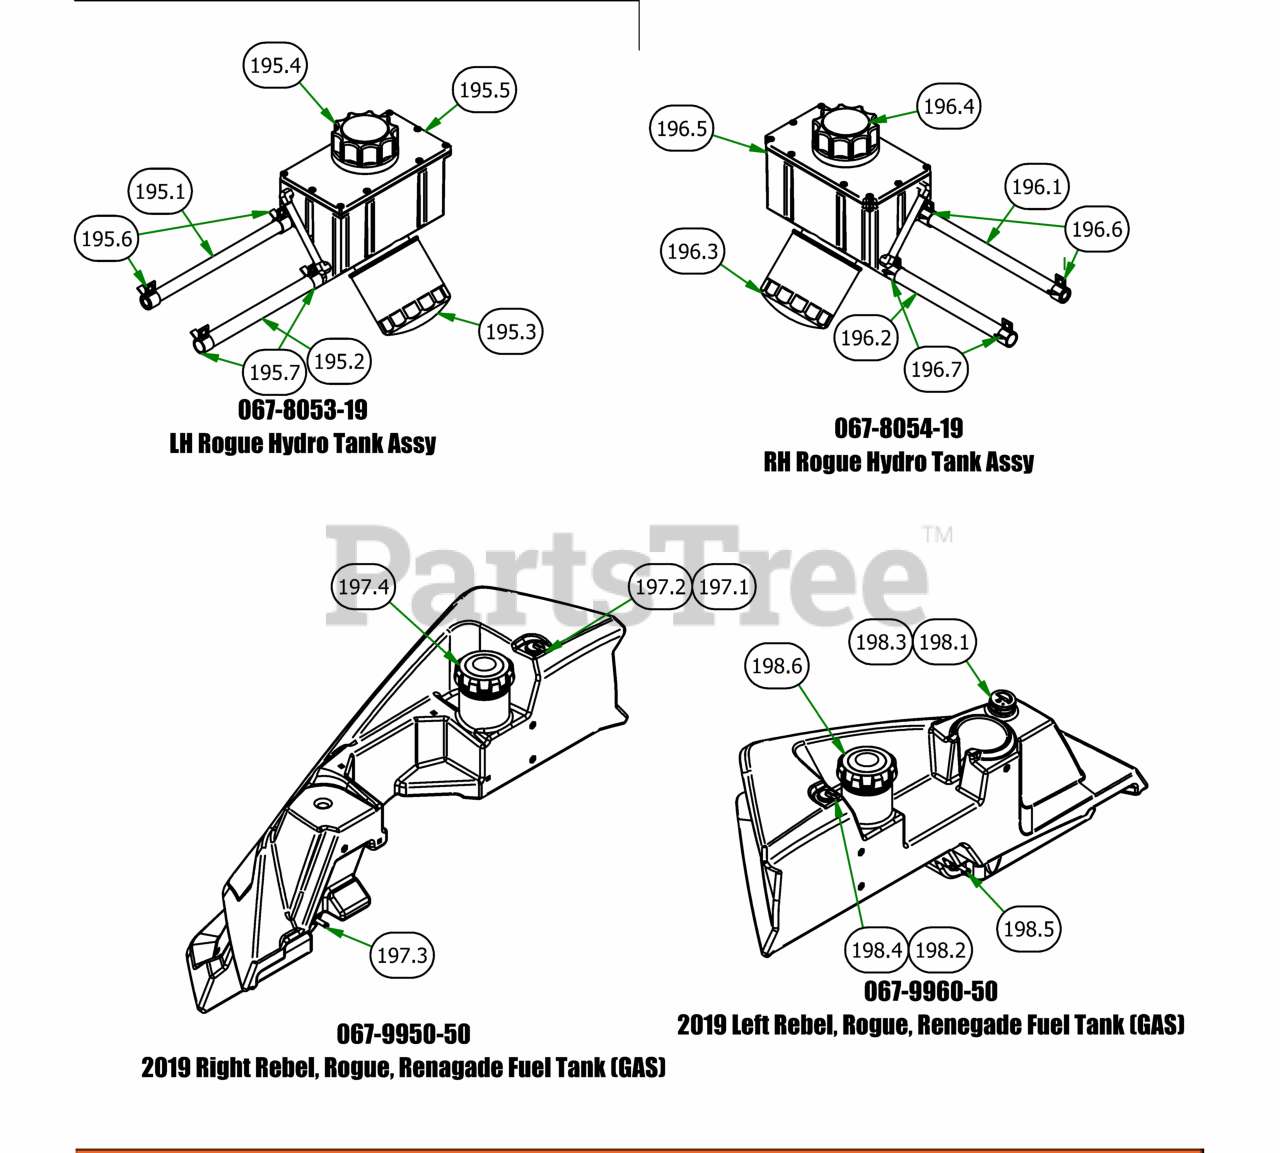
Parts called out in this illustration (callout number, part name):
195.1	3/8" Clear Hose x 4 1/2"
195.2	1/2 Clear Braded Hose Priced/Foot x 9.5"
195.3	Hydraulic Filter
195.4	Hydraulic Tank Cap W/Dipstick
195.5	2019 Left Outlaw Gen2 Hydro Tank Suspension Only
195.6	3/8" Hose Clamp
195.7	1/2 Hose Clamp
196.1	3/8" Clear Hose x 4 1/2"
196.2	1/2 Clear Braded Hose Priced/Foot x 9.5"
196.3	Hydraulic Filter
196.4	Hydraulic Tank Cap W/Dipstick
196.5	2019 Right Outlaw Gen2 Hydro Tank Suspension Only
196.6	3/8" Hose Clamp
196.7	1/2 Hose Clamp
197.1	Roll Over Valve Grommet
197.2	Rollover Valve
197.3	Fuel Pick-up
198.1	Fuel Gauge with Grommet
198.2	Roll Over Valve Grommet
198.3	Fuel Gauge Grommet
198.4	Rollover Valve
198.5	Fuel Pick-up
